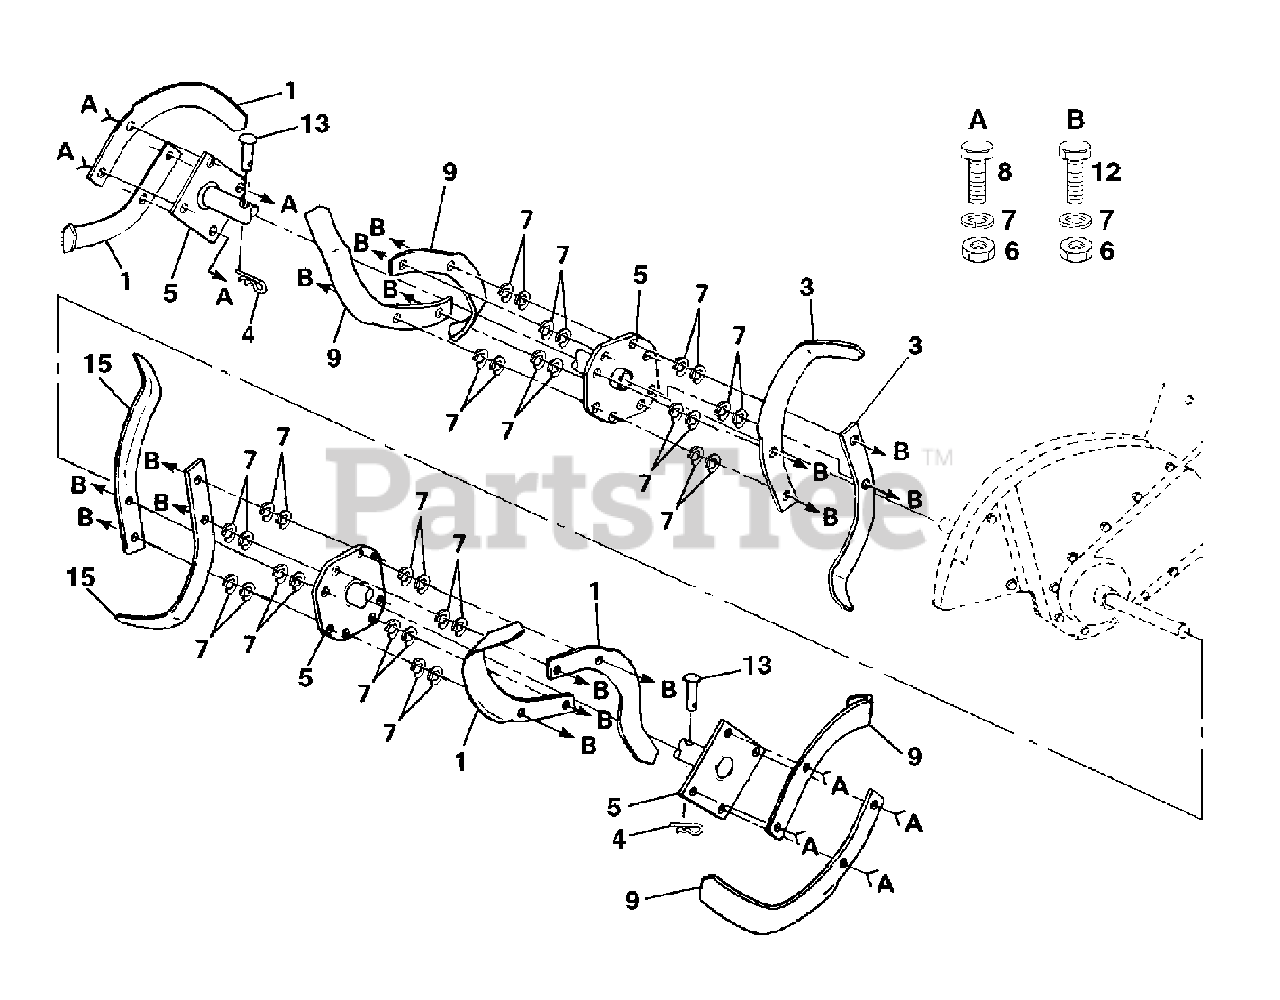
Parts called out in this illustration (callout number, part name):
1	Tine, Outer, L.H.
3	Tine, Inner, L.H.
4	Retainer, Spring Zinc
5	Assembly, Hub and Plate
6	Nut, Hex 3/8-24
7	Washer, Lock 3/8
8	Bolt, Hex 3/8-24 x 1
9	Tine, Outer, R.H.
12	Bolt H 3/8-24 x 1-1/2
13	Clevis Pin
15	Tine R.H.
